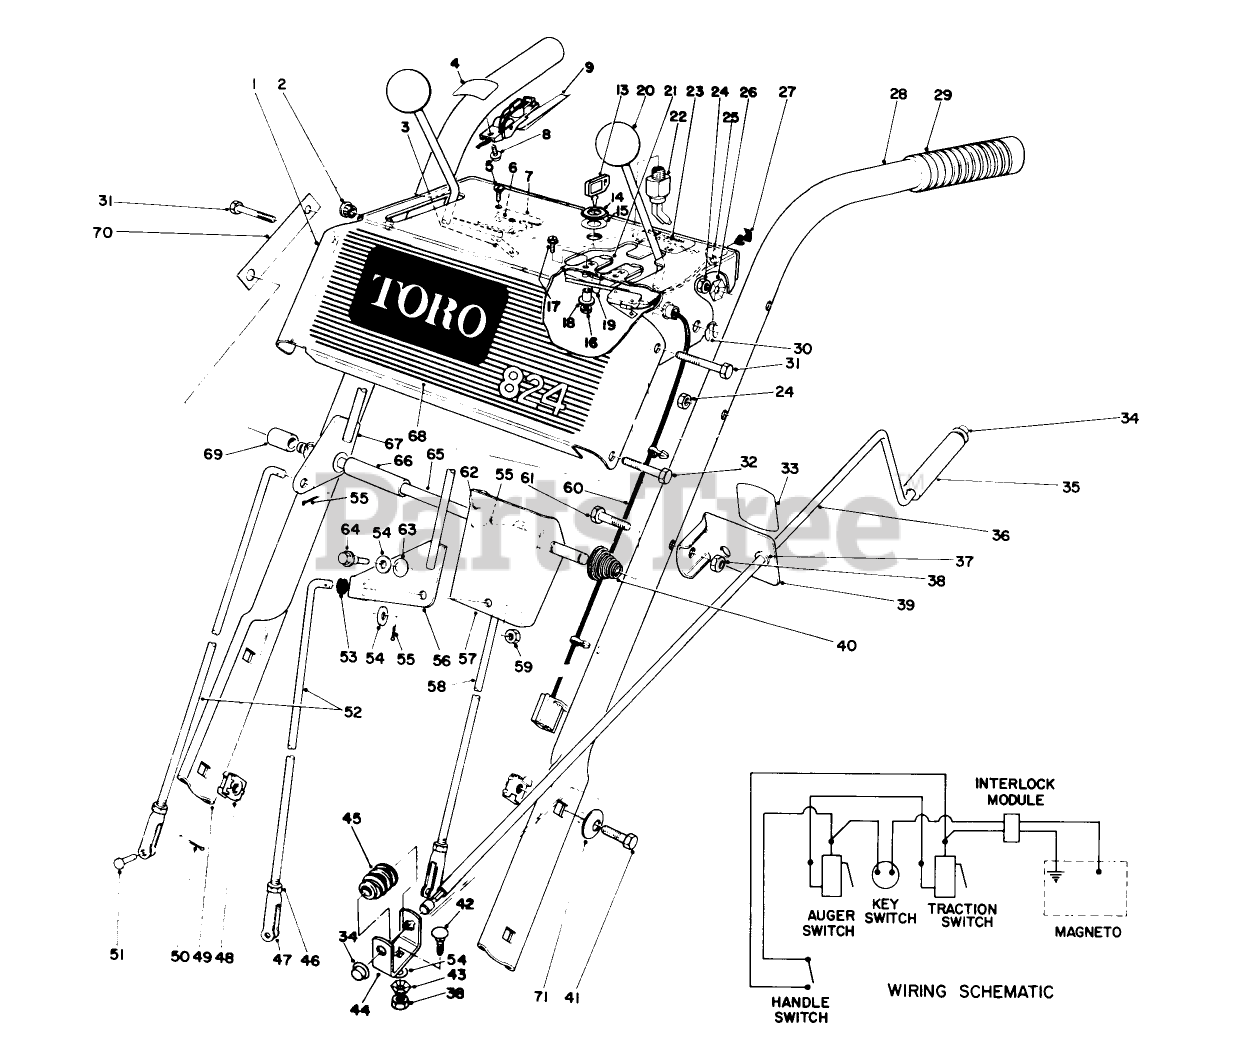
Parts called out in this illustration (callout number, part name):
1	PANEL W/DECAL
2	BUSHING NYLON
3	NUT-SPEED
5	SCREW-SPH
6	SWITCH-MICRO
8	SCREW-HWH
13	KEY-IGNITION
14	NUT-HH
15	WASHER-LOCK
16	NUT-LOCK, NI
17	10-24 X 7/8 RND HD MS
18	INTERLOCK SPACER
19	INTERLOCK SPRING
21	INTERLOCK SLIDE
22	ON OFF SWITCH
23	INSTRUCTION DECAL
24	NUT-LOCK, NI
29	HANDLE GRIP
30	RING-CLIP
31	SCREW-HH
32	SCREW-HH
33	DECAL-CHUTE DIRECTION
34	NUT-PUSH
38	NUT-LOCK, NI
40	CONICAL SPRING
41	SCREW-HH
42	SCREW-CARR
43	WASHER-LOCK
44	BRACKET-WORM
45	GEAR-WORM, CHUTE
46	NUT-HJ
50	PIN-COTTER
51	PIN-CLEVIS
53	GROMMET-RUBBER
54	WASHER-FLAT
55	PIN-COTTER
59	NUT-LOCK, CONE
61	SCREW-HH
62	WASHER-FLAT
65	PIVOT ROD
66	SHIFT LEVER SPACER
67	LEVER WA
68	DECAL - ESCUTCHEON 824
69	AUGER LEVER SPACER
71	WASHER-BELLEVILLE
